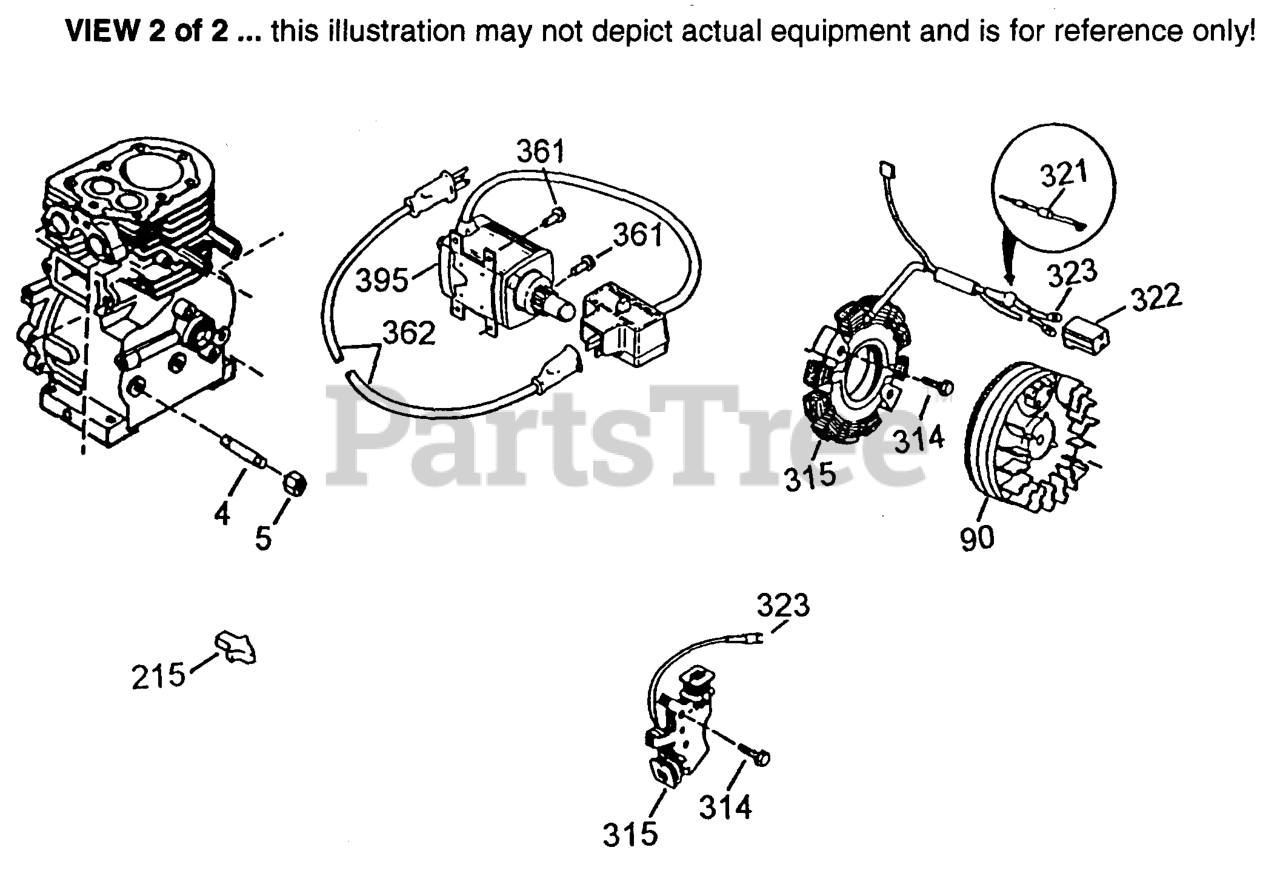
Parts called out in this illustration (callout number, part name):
4	PIPE NIPPLE
5	PIPE CAP
90	FLYWHEEL
370B	DECAL
370E	DECAL
408	SNOW SEAL
